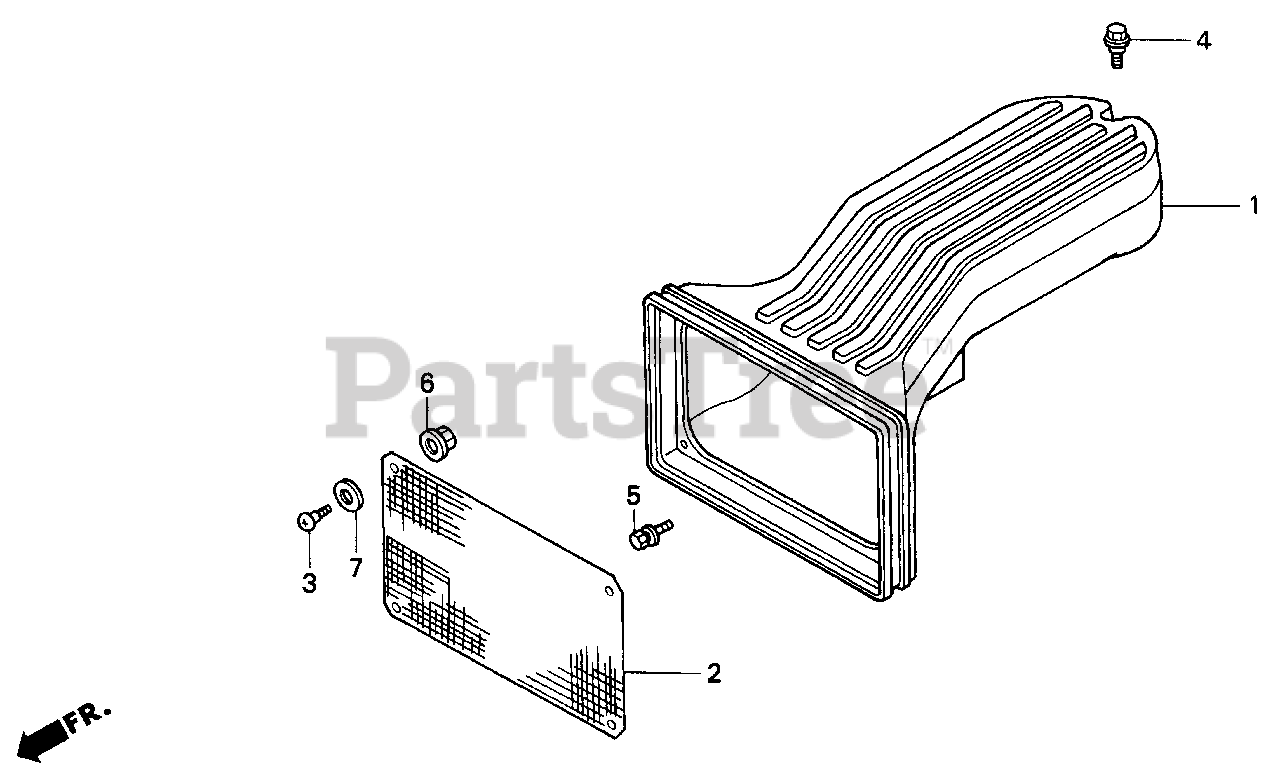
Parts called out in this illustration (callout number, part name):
1	GUIDE, AIR
2	SCREEN, DUST
3	SCREW, PANEL SETTING (INNER)
4	BOLT (6MM)
5	BOLT-WASHER (6X12)
6	NUT, FLANGE (6MM)
7	WASHER, PLAIN (8MM)
